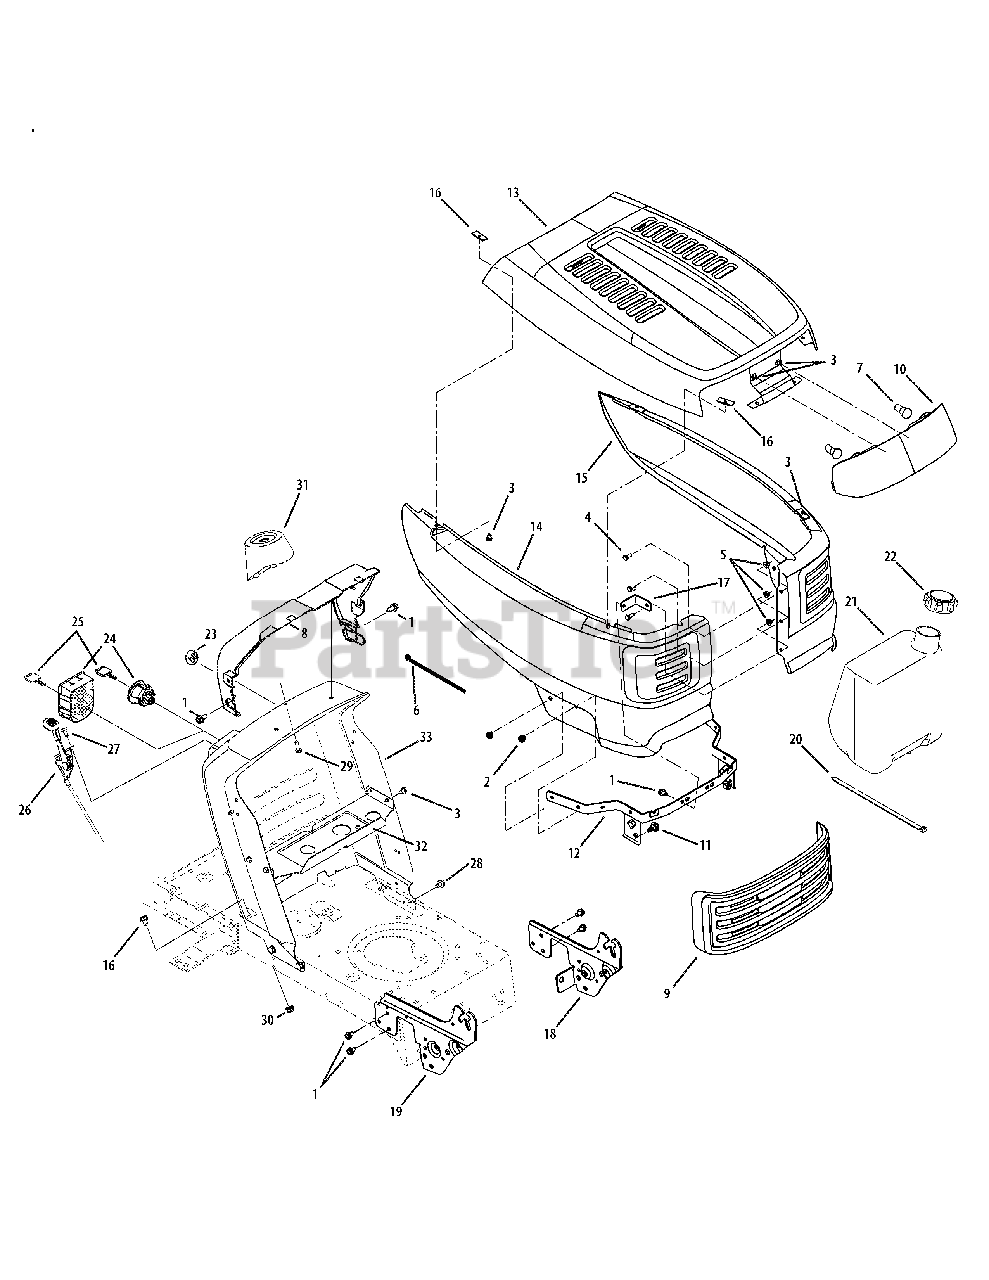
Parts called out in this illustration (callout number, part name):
1	Screw, tt, 5/16-18, .750
2	Screw, tt, 5/16-18, 0.375
3	Screw, tt, 1/4-20, 0.500
4	Hex Screw, 1/4-20, .620
5	Nut, Flange Lock, 1/4-20
6	Cable tie, 3/16 X .05 X 7.4
8	Collar, dash, 1/3/5/K/T Sty Lt-5
9	Ins, grill, T-Style
10	Lens, T-Style
11	Screw, Shldr, .43x.29, Tt, 5/16-18
12	Bracket, pivot, hood
15	Side Panel, LH W/O Window
16	Fastener, Hood T-Style
17	Hood Bracket, Front
18	Bracket Support, Pivot LH
19	Bracket Support, Pivot RH
21	Fuel Tank
22	Fuel Cap
24	Key Switch
24	Key Switch Module
26	Throttle/Choke Cable
27	Screw, 1/4-20 x .500
28	Screw, 5/16-18 x 0.625
29	Screw, 1/4-15 x 0.750
30	Flangelock Nut, 5/16-18
31	Steering Support
32	Gas Tank Support Bracket
38	Fuel Tank, 1.5 Gallon
39	Fuel Cap
40	Throttle/Choke Cable
